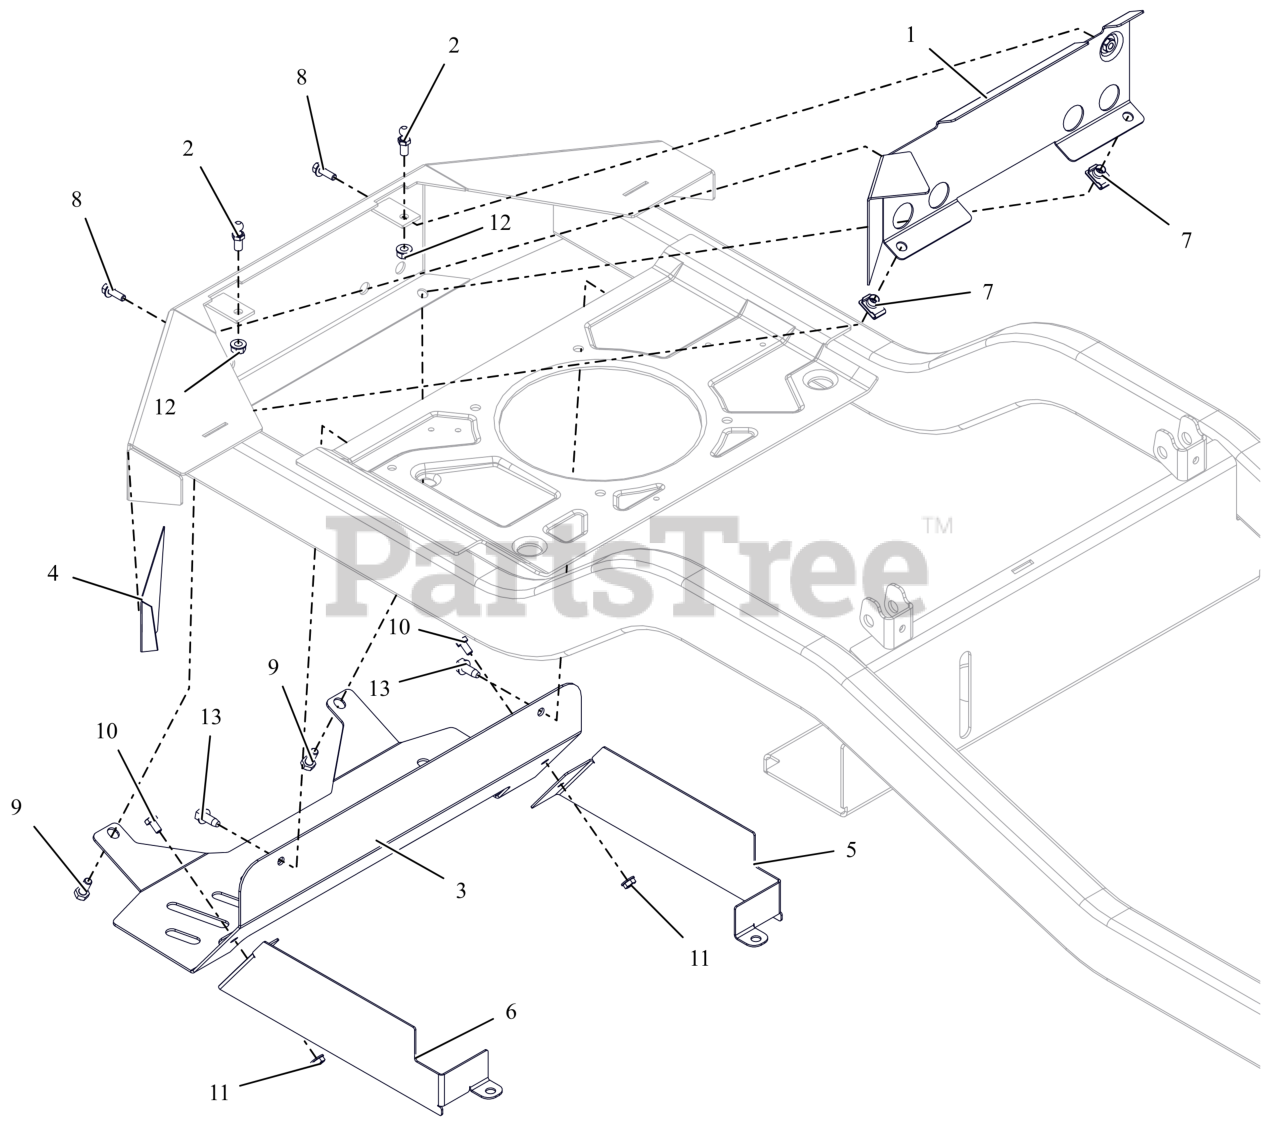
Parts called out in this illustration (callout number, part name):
1	WMT, HEAT BAFFLE
2	STUD- BALL
3	SHIELD, HEAT (HD)
4	TAPE, HEAT DEFLECTOR
5	GUARD,REAR CLUTCH LH
6	GUARD,REAR CLUTCH RH
7	NUT-CLIP RETAINER 5/16-18X.56
8	BLT,HEX-FLG .25-20X.75 G5 BFP
9	BLT,HEX .31-18X.75 G5 ZCC
10	BLT,HEX .25-20X.50 G5 ZCC
11	NUT-LK-TOP-FLG .250-20 GF ZCC
12	NUT,LK-CTR-FLG .31-18 GF ZCC
13	SCR,TAP .312-18X.75 HWH TR ZCC
